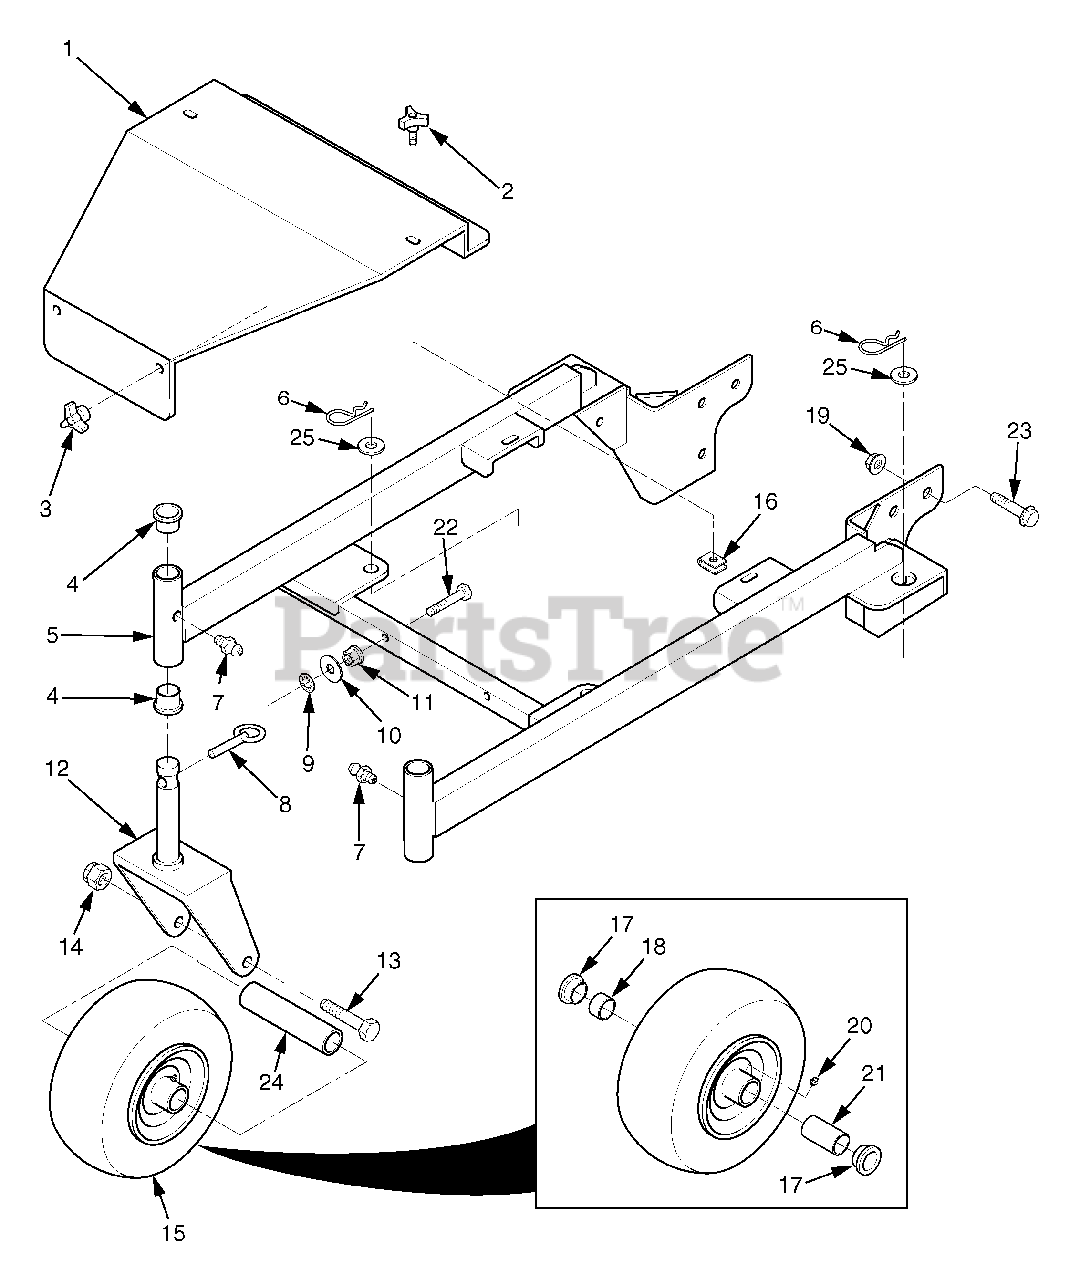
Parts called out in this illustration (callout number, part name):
1	Belt Cover With Decal
2	Knob With Stud
3	Knob, Deck Cover Mounting
4	Bushing, Caster
5	Frame Weldment, Deck Mounting - 36"
6	Hair Pin Cotter, .177" x 3-1/4"
7	Grease Fitting Str. 1/4-28 Self Tap
8	Quick Pin, .438" Dia.
9	Nut, Push-On - 3/8" Dia.
10	Flatwasher, 3/8" (.391 x .938 x .105)
11	Nut, 3/8-16 Serrated Flange Hex Head
12	Yoke, Caster Wheel
13	Capscrew, Hex Head 1/2-13 x 6-1/2"
14	Locknut, 1/2-13 Elastic Stop
15	Flat Free Tire Assy.
16	U-Nut, 3/8-16
17	Retainer
18	Roller Bearing
19	Nut, 1/2-13 Spiralock
20	Grease Fitting 1/4-28, 45 Degree
21	Roller Bearing .625 x 3.25"
22	Capscrew, Hex Head 3/8-16 x 2-1/4"
23	Capscrew, 1/2-13 x 1" Serrated Flange Hex Head
24	Sleeve, Caster Wheel
25	Flatwasher, 5/8" - (.688 x 1.75 x .134)
